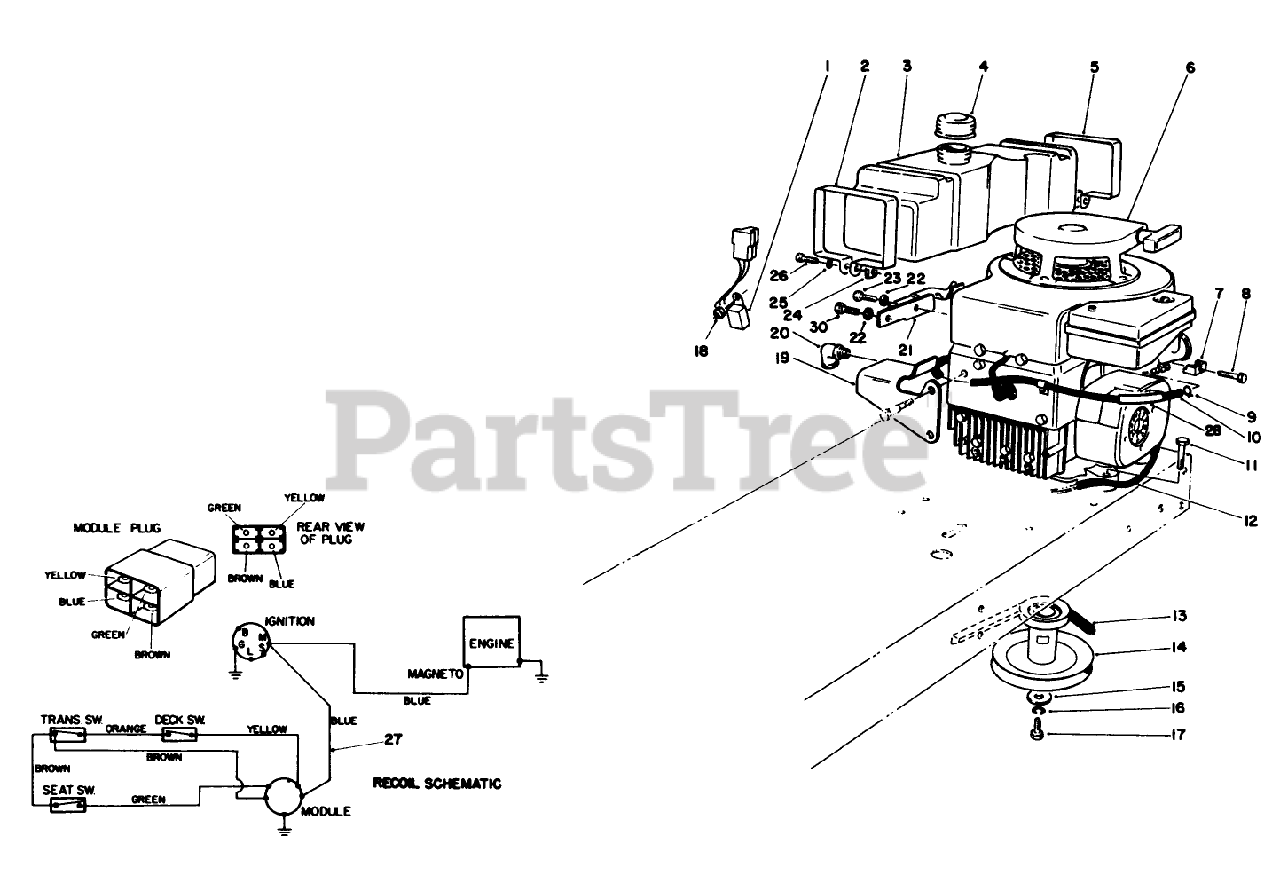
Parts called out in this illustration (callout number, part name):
2	Retainer-Tank Front
3	TANK-5 QT GAS
4	GAS CAP ASM
5	Retainer-Tank Rear
6	Engine
7	CLAMP-CASING
8	SCREW (F/W ENGINE)
9	CLAMP-HOSE
11	SCREW-HH
12	Cover-Protective
13	V-BELT, TRACTION
14	PULLEY
15	WASHER-FLAT
16	WASHER-LOCK
17	SCREW-HH
19	Bracket-Mount Tank Front
20	ELBOW-STREET, 90 DEG
21	Bracket-Mount Tank Rear
22	WASHER-PLAIN
23	SCREW-HH
24	NUT-SQUARE
25	WASHER-LOCK
26	SCREW-HSH
28	SUPPORT-FUEL LINE
30	Screw
